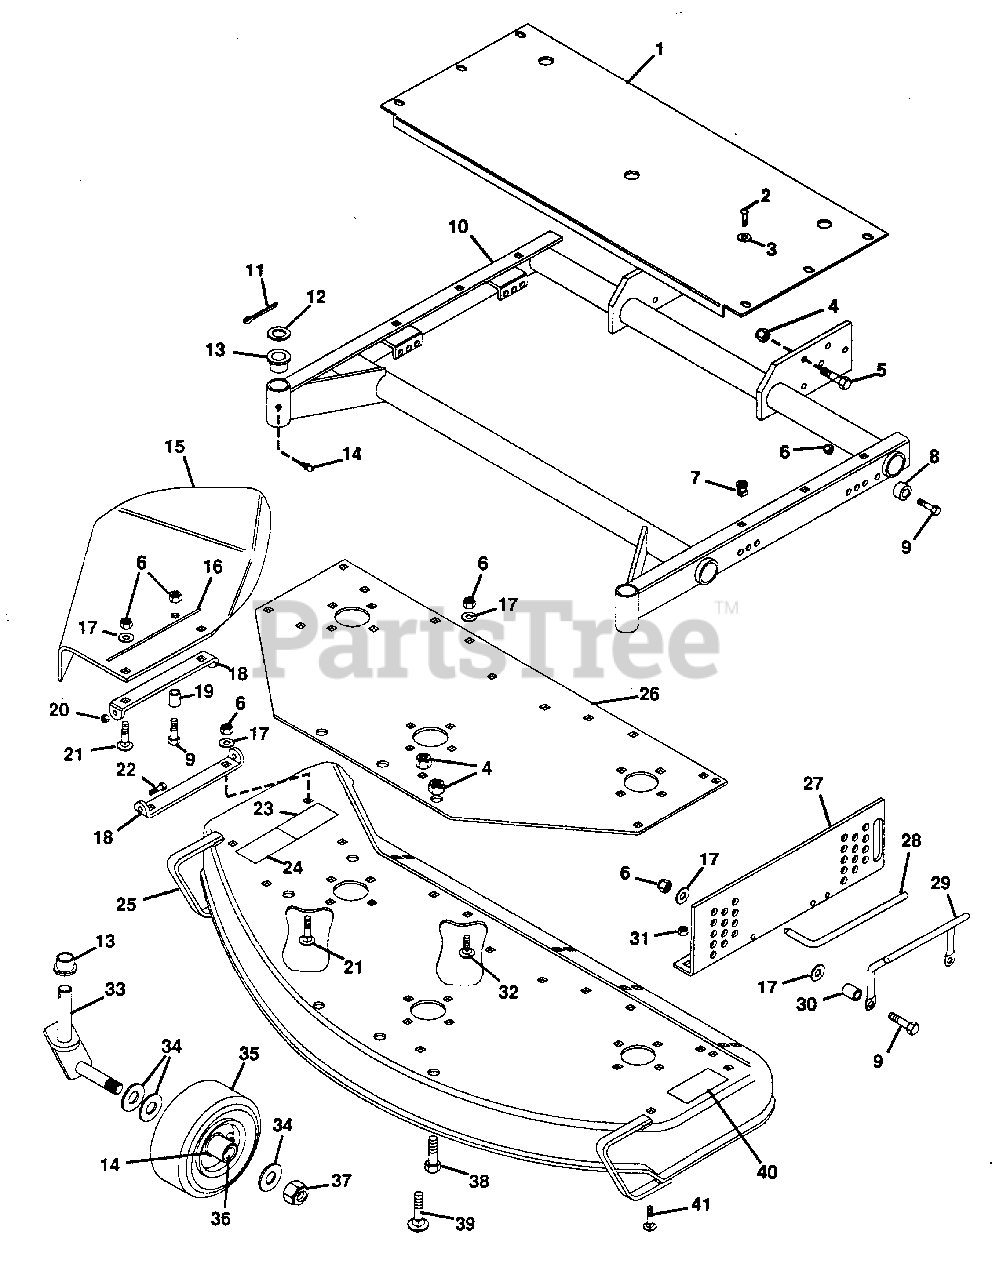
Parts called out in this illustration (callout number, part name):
1	GUARD, 50" PM18-H BELT
2	SCREW, TAPPING 1/4-20X.625 P/HD
3	WASHER, FLAT .281X.625X.065
4	NUT, LOCK 1/2-13
5	BOLT, HEX 1/2-13X1.50
6	NUT, LOCK 3/8-16
7	GROMMET, PLASTIC
8	BUSHING .391X.622X.670
9	BOLT, HEX 3/8-16X1.50
10	WELDMENT, MOWER FRAME
11	PIN, COTTER .187X1.50
12	RACE, BEARING THRUST
13	BUSHING, PIVOT
14	FITTING, LUBE 1/4-28
15	SHIELD, SAFETY EXT. 50" MOWER
16	STRIPE
17	WASHER, FLAT .406X.812X.065
18	BRACKET, CHUTE
19	STOP, CHUTE
20	NUT, LOCK 1/4-20
21	BOLT, 3/8-16X1.00 RD HD SQ NK
22	BOLT, HEX 1/4-20X.875
23	DECAL, DANGER HAND
24	DECAL, WARNING EYE
25	WELDMENT, 50" MOWER DECK
26	ASSEMBLY, 50" SUPPORT PLATE
27	BRACKET, MOWER SIDE SUPPORT L.H.
27	BRACKET, MOWER SIDE SUPPORT R.H.
28	PIN, MOWER LOCKING
29	HANDLE
30	BUSHING
31	NUT, LOCK 5/16-18
32	BOLT, CARRIAGE 3/8-16X.75
33	WELDMENT, CASTER FORK
34	WASHER, FLAT .812X1.496X.134
35	WHEEL, GAUGE
36	BEARING, GAUGE WHEEL
37	NUT, LOCK 3/4-10
38	BOLT, HEX 1/2-13X1.25
39	BOLT, 1/2-13X1.00 RD HD SQ NK
40	DECAL, DANGER FOOT
41	BOLT, CARRIAGE 5/16-18X1.00
NS	BAFFLE
NS	DECAL, GRAVELY LOGO
NS	DECAL, PRO-50
